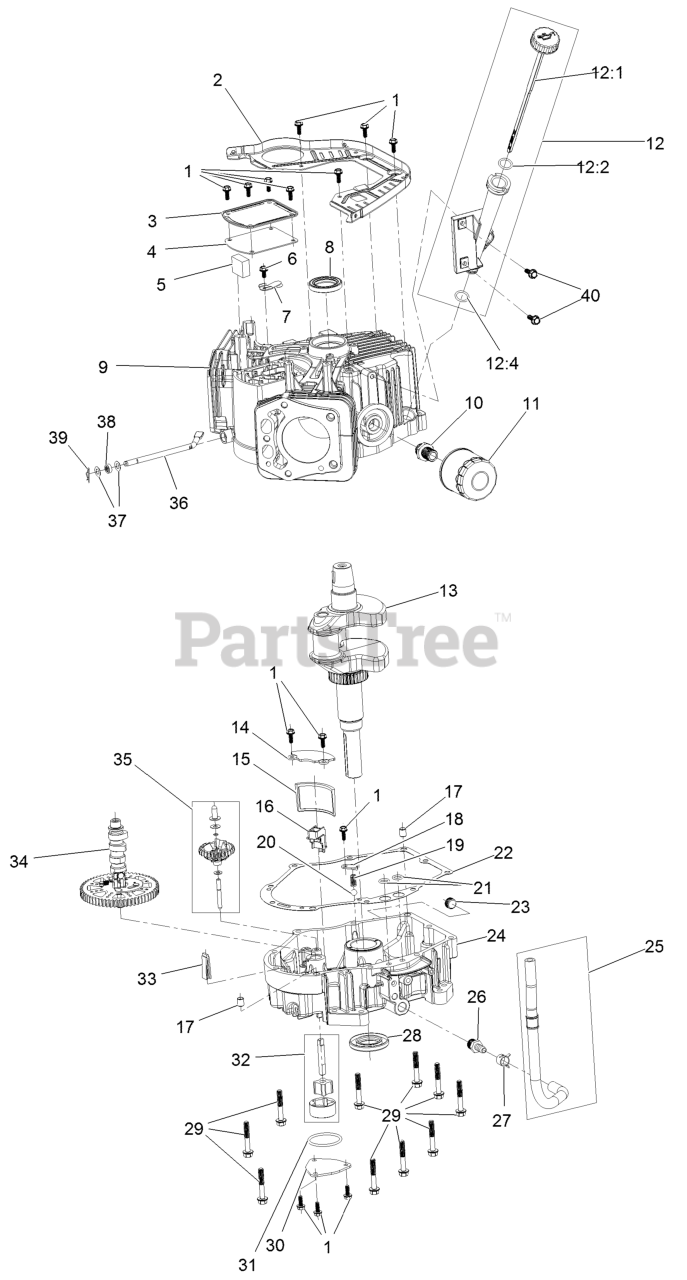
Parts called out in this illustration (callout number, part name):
1	SCREW-HHF
3	COVER-BREATHER
4	GASKET-BREATHER
5	FILTER-BREATHER
6	SCREW-HHF
7	VALVE-BREATHER
8	SEAL-OIL
9	CRANKCASE
12	OIL TUBE ASM
12:1	DIPSTICK
13	CRANKSHAFT
14	COVER-SCREEN, OIL
15	SCREEN-OIL
16	RETAINER-SCREEN
17	PIN-DOWEL
18	PLATE-RETAINER
20	VALVE-BALL
22	GASKET-COVER, CRANKCASE
23	PLUG-DRAIN
24	COVER-CRANKCASE
25	OIL DRAIN HOSE ASM
26	FITTING-HOSE
27	CLAMP-HOSE
29	SCREW-HHF
30	COVER-OIL PUMP
32	OIL PUMP ASM
33	DEFLECTOR-OIL, RUBBER
36	SHAFT-GOVERNOR
37	WASHER-PLAIN
38	SEAL-OIL
39	PIN-HAIR
40	SCREW-HHF
